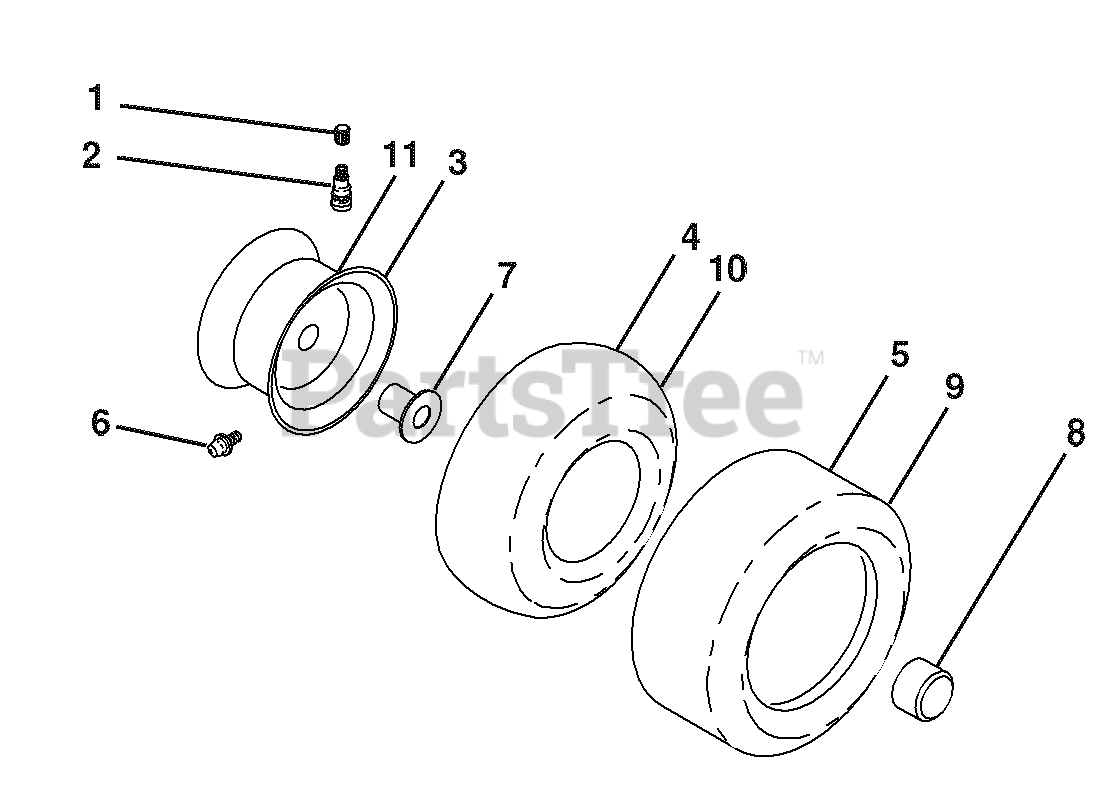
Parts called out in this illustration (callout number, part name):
1	Cap Valve Tire
2	Stem Valve
3	Rim Front Service
4	Tube Front
5	Tire Front 15 x 6.0-6 Service
6	Fitting Grease
7	Bearing Flange
8	Cap Axle Blk 1 50 x 1 00
9	Tire R T 20 x 10-8 Service
10	Tube Rear
11	Rim Asm 8" Rear Service
